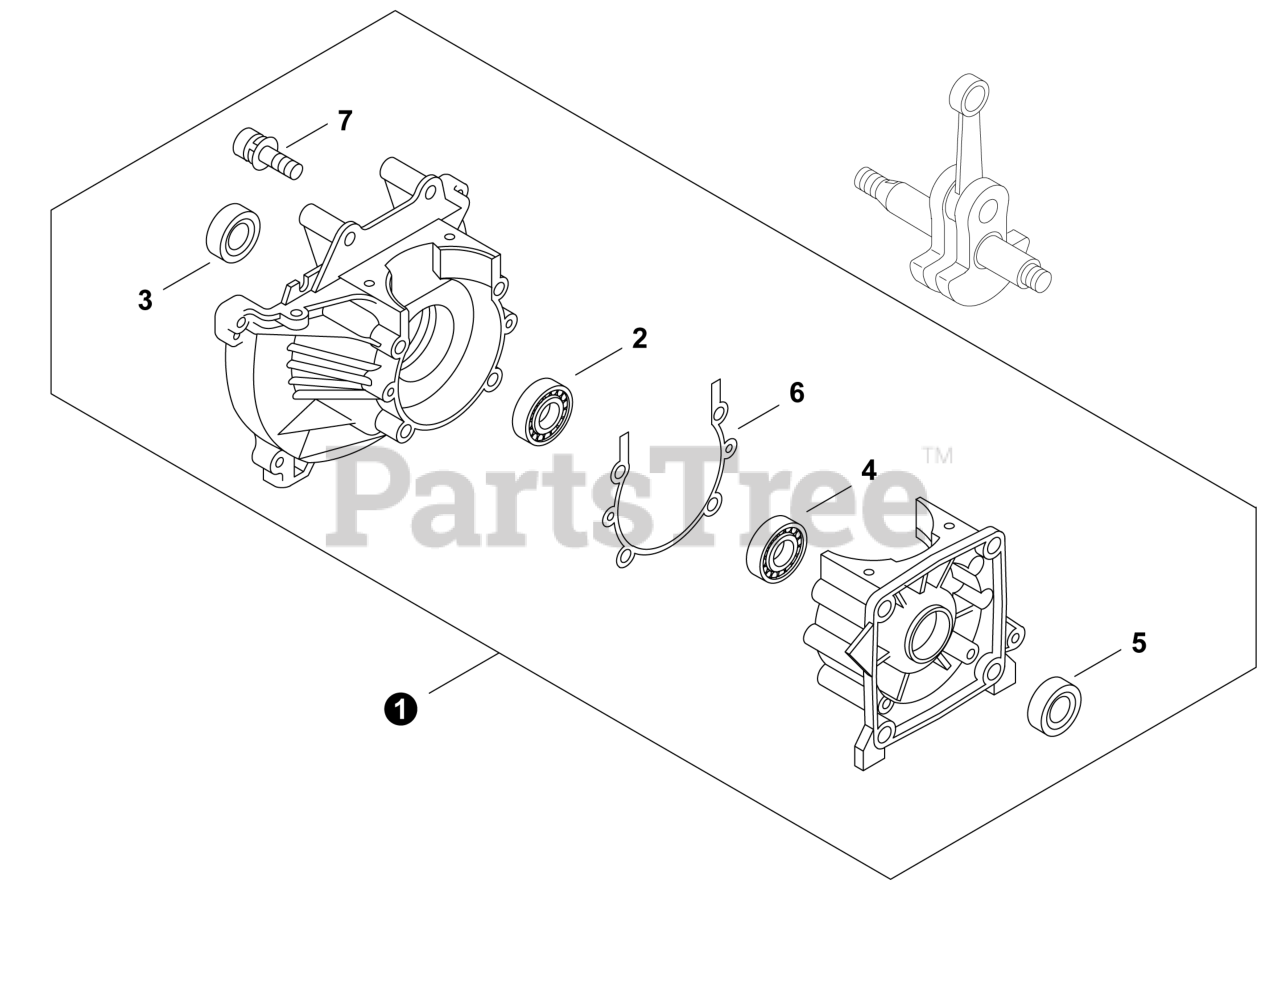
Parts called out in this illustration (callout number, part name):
1	CRANKCASE KIT
2	BEARING, BALL 6201
3	SEAL, OIL
4	BEARING, BALL 6202
5	SEAL, OIL 12
6	GASKET, CRANKCASE
7	BOLT M5×35
